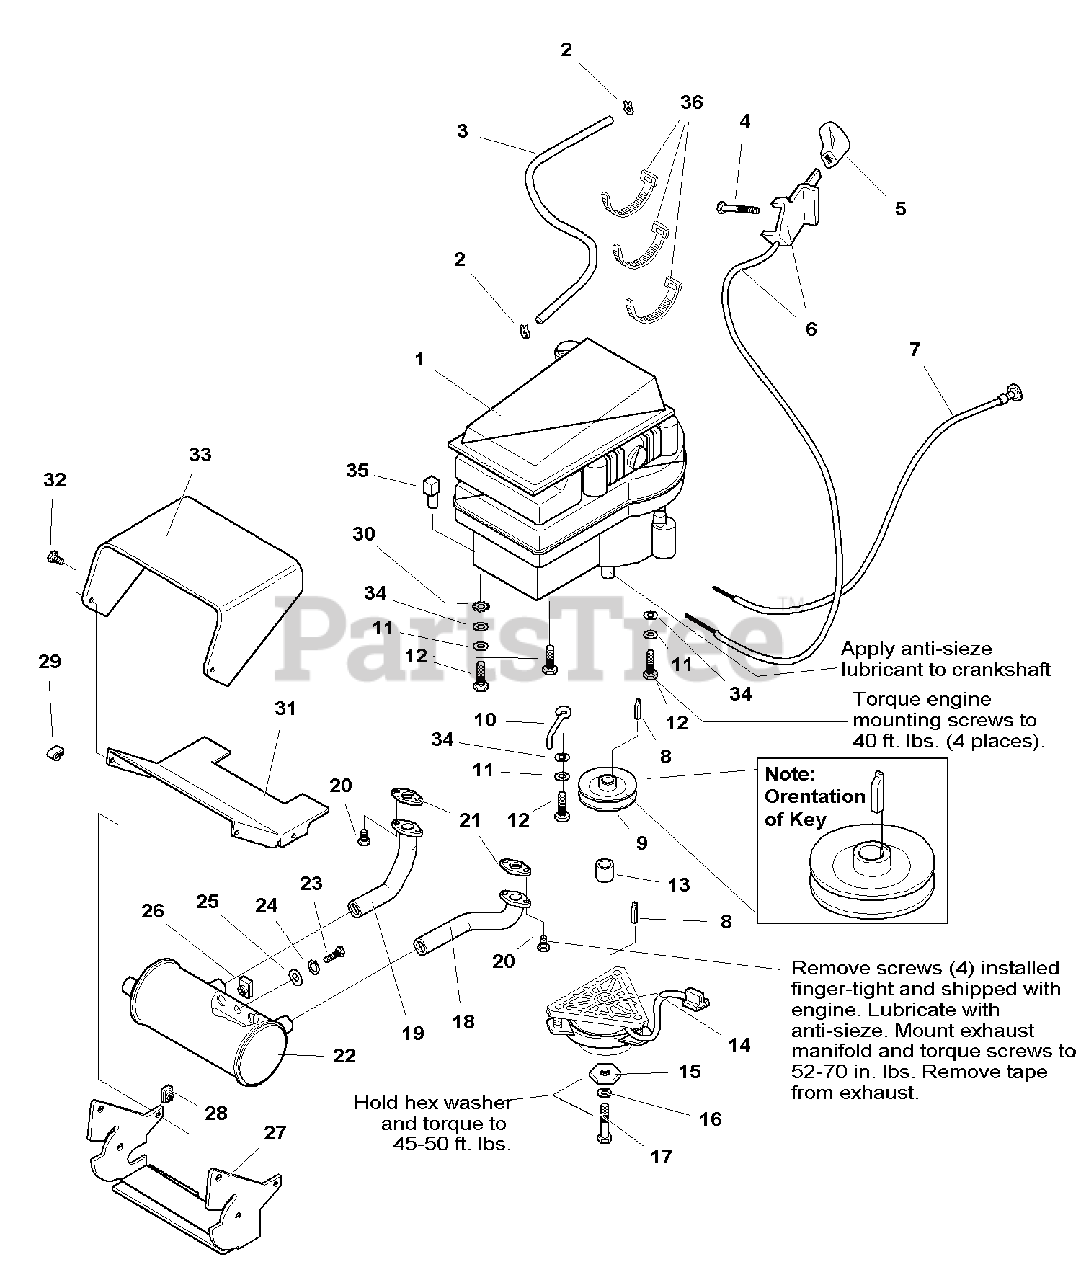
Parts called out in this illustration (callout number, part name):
1	ENGINE, 17HP Kawasaki
2	CLAMP, Hose
3	HOSE, Fuel, 38" Long
4	CAPSCREW, Hex Head, Plastite, 1/4-20 x 1/2
5	KNOB, Throttle
6	THROTTLE CONTROL ASSEMBLY
7	CABLE, Choke Control
8	KEY, Hi-Pro
9	PULLEY ASSEMBLY
11	WASHER, Lock, 5/16
12	CAPSCREW, Hex Head, M8 - 1.25 x 40mm
14	ELECTRIC CLUTCH ASSEMBLY, PTO
15	WASHER, Hex
16	WASHER, Lock, 7/16
17	CAPSCREW, Hex Head, M10 - 1.5 x 100mm
18	MANIFOLD PIPE, LH
19	MANIFOLD PIPE, RH
20	CAPSCREW, Hex Socket Head, M8 - 1.25 x 20mm
21	GASKET
23	CAPSCREW, Hex Head, 5/16-18 X 1
24	WASHER, Lock, 5/16
25	WASHER, 5/16
26	NUT, Speed, 5/16-18
27	DUCT, Lower Exhaust
28	PAL NUT, 1/4-20
29	CLIP
30	WASHER, Lock, External Tooth, 5/16
31	DUCT, Upper Exhaust
32	CAPSCREW, Hex Head, Whiz Lock, 1/4-20 x 5/8
33	DUCT, Upper
34	WASHER, Flat, 5/16
35	VALVE, Oil Drain
36	TIE, Self-Locking
